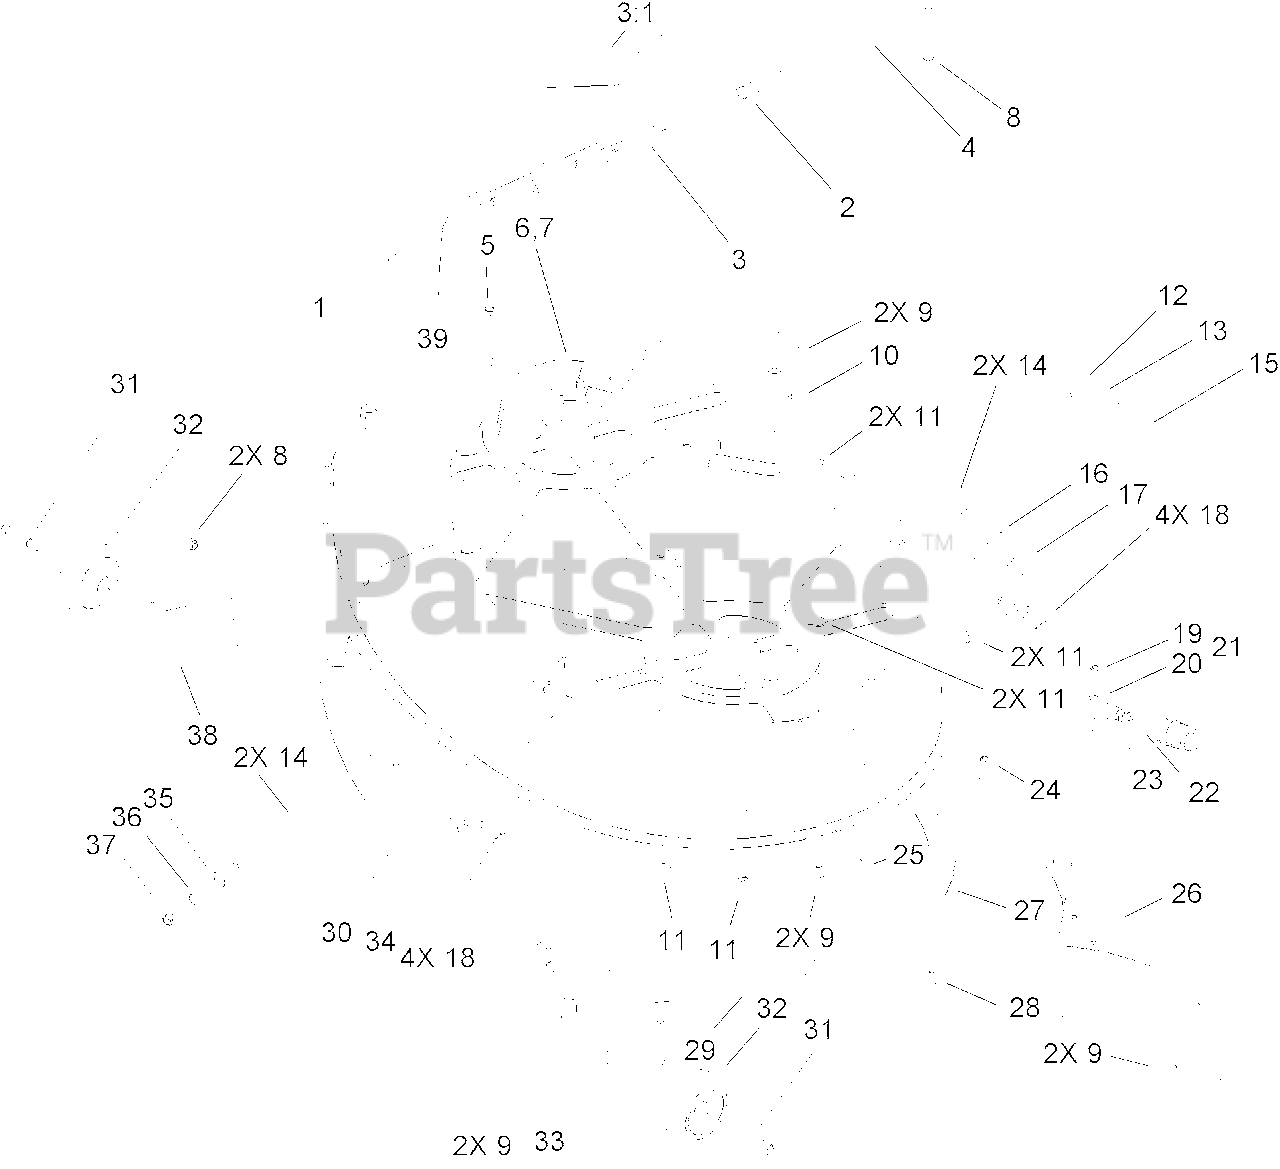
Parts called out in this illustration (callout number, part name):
1	42IN DECK ASM
3	DEFLECTOR ASM
3:1	DECAL-DANGER
4	ROD-PIVOT
6	LH BELT GUIDE-DECK
7	RH BELT GUIDE-DECK
8	NUT-LOCK, NI
9	SCREW-HH
10	WASHER-FLAT
12	WASHER-PIVOT
13	TRUNNION-HOC
14	ROD-HANGER
15	BOLT-SHOULDER
16	LINK-ADJUSTING, HOC
17	WASHER-HARDENED
18	PIN-HAIR
19	NUT-LOCK, NI
20	WASHER-FLAT
21	CONNECTOR-HOSE
23	FITTING-WASHOUT
24	NUT-LOCK, NI
25	SCREW-CARR
26	REAR BAFFLE ASM
27	RING-BLOW OUT, SIDE
28	SCREW-HH
29	RING-BLOW OUT, SIDE
30	RING-BLOW OUT
31	BOLT-WHEEL
32	WHEEL-GAGE
33	BRACKET-GAGE WHEEL, FRONT (LH)
34	WASHER-FLAT
35	WASHER-FLAT
36	NUT-HEX
37	NUT-LOCK, NI
38	BRACKET-GAGE WHEEL, FRONT (RH)
